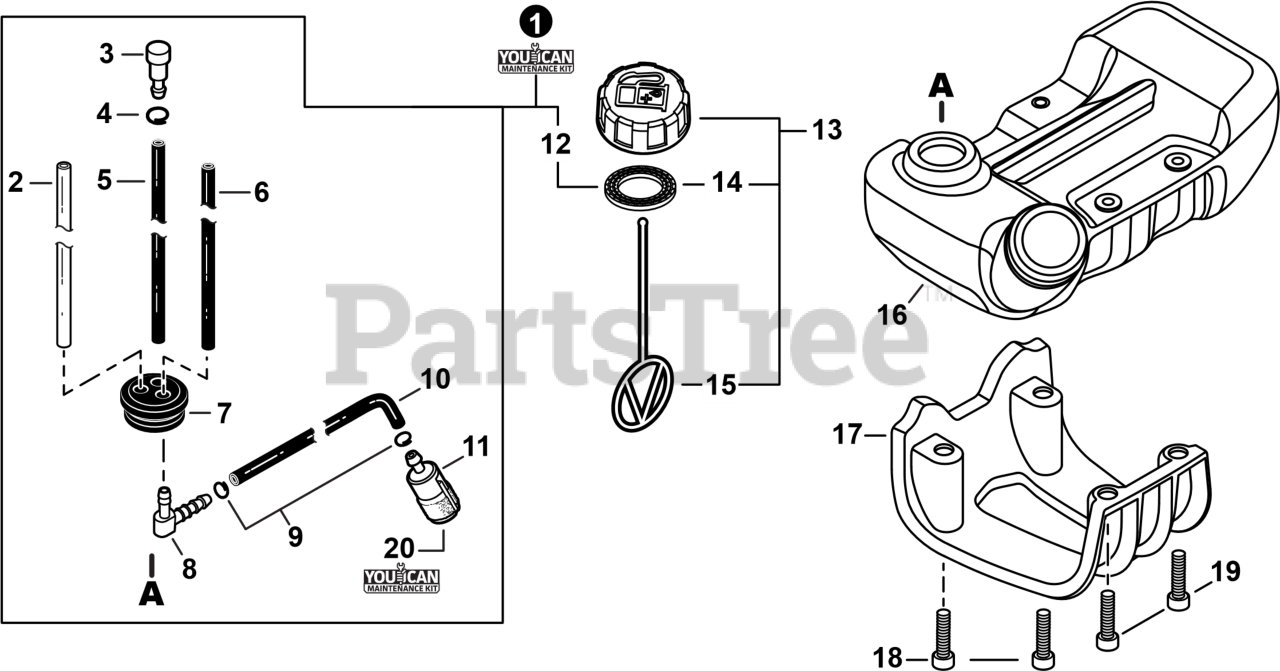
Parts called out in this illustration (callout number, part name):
1	FUEL SYSTEM KIT - YOUCANT
2	PIPE, FUEL 3×6×85 CLEAR
3	VENT ASSY
4	CLIP Ø6.5 MM
5	PIPE, FUEL 3X6X95 BLACK
6	PIPE, FUEL 3×5.5×70 BLACK
7	GROMMET, FUEL
8	CONNECTOR, PIPE
9	CLIP Ø6
10	PIPE, FUEL 3X5X140X35 BLACK
11	FILTER, FUEL
12	GASKET, FUEL CAP
13	CAP ASSY, FUEL
14	GASKET, FUEL CAP
15	CONNECTOR, CAP L= 123
16	TANK, FUEL
17	GUARD, FUEL TANK
18	BOLT, TORX 5×25
19	BOLT, TORX 5×20
20	TUNE-UP KIT - YOUCANT
